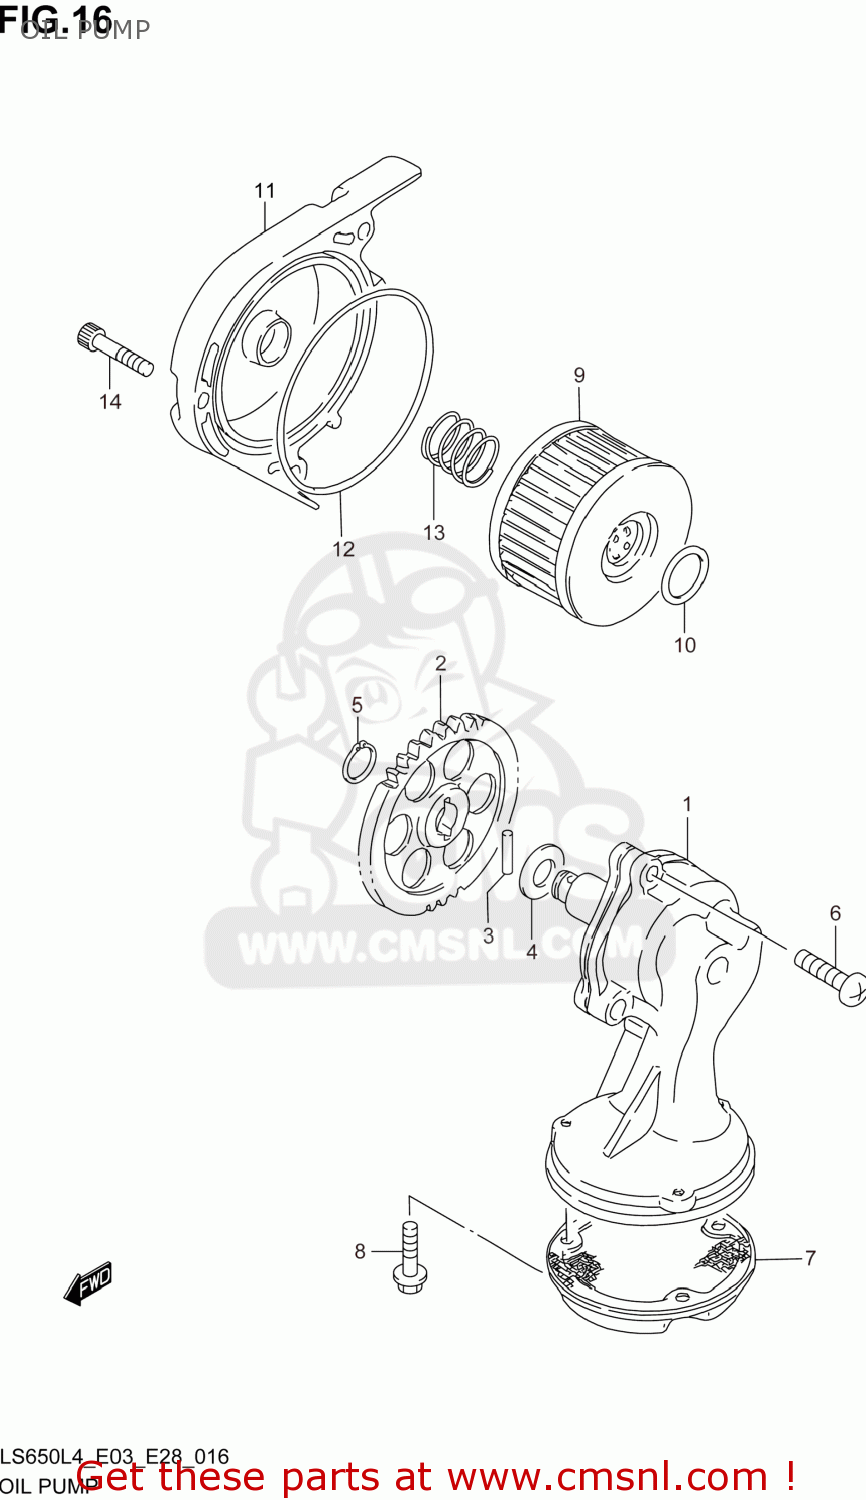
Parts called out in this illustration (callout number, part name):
1	PUMP ASSY,ENGINE OIL
2	GEAR,ENG OIL PUMP DRIVEN
3	PIN(4X15.8)
4	SHIM(10X18X0.5)
5	CIRCLIP
6	SCREW
7	STRAINER,ENGINE OIL
8	BOLT
9	FILTER ASSY,ENGINE OIL
10	O RING(D:2.4,ID:15.8)
11	CAP,OIL FILTER
12	O RING(D:2.4,ID:73)
13	SPRING
14	BOLT(6X25)
